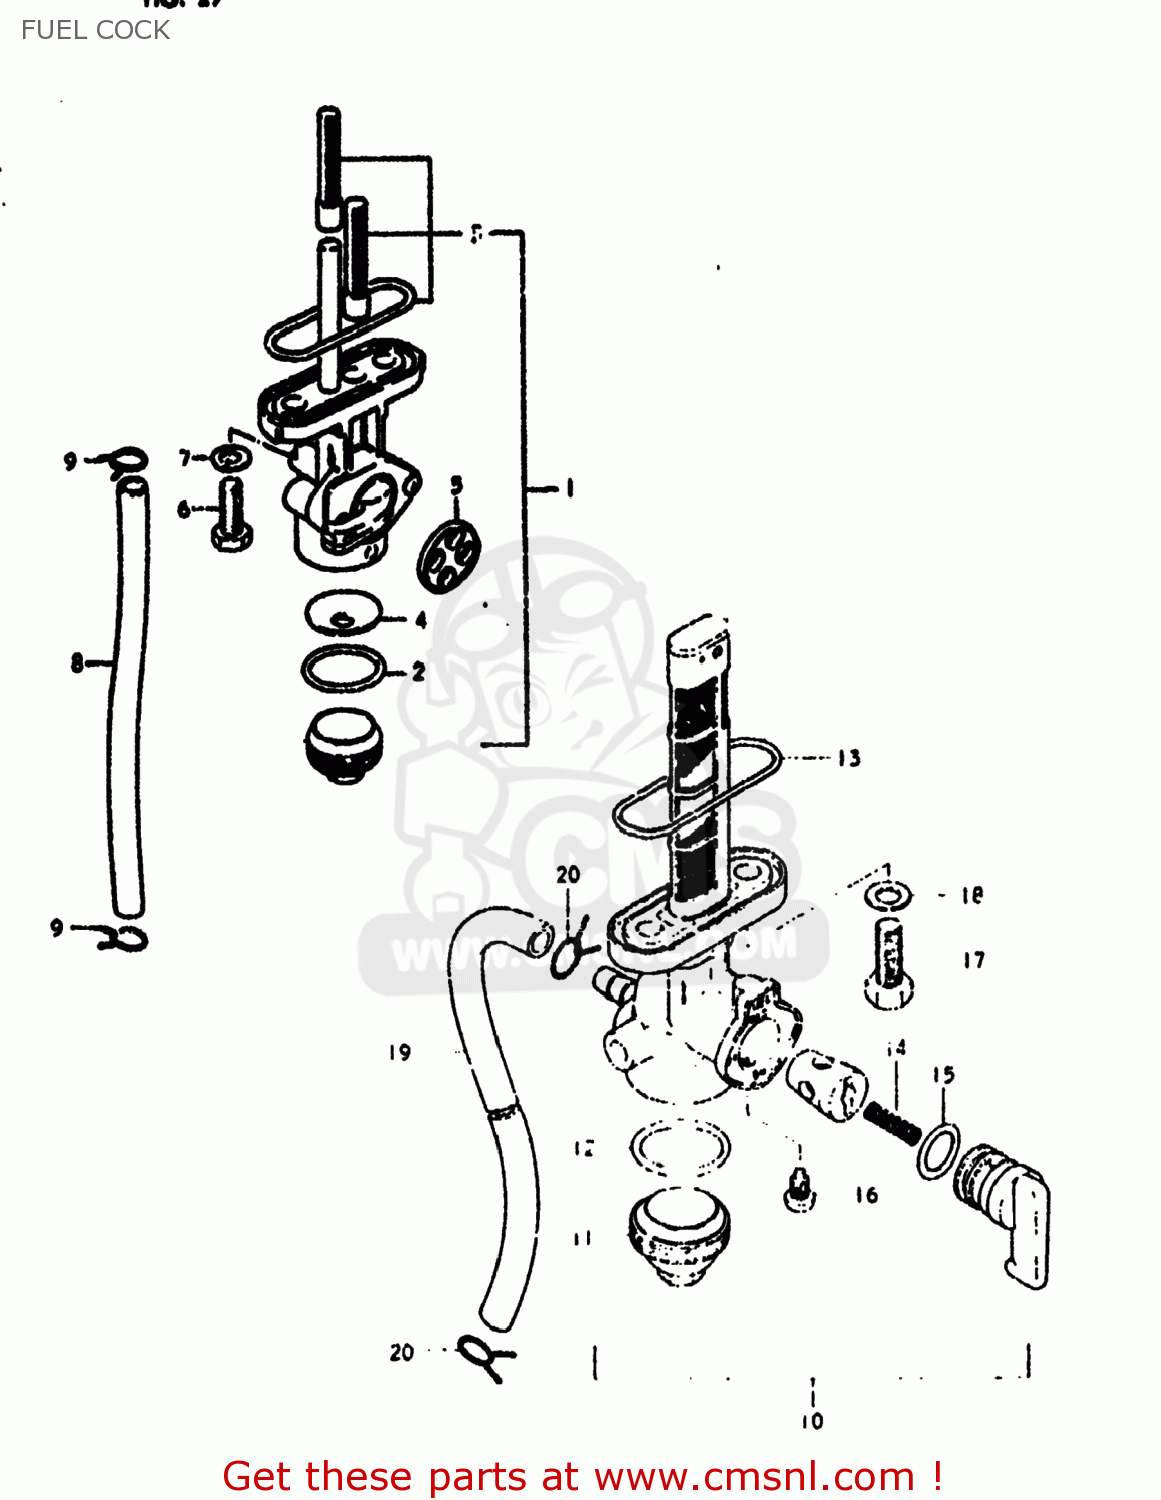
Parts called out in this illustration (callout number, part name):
1	COCK ASSEMBLY,FUEL
2	GASKET,FILTER (NAS)
3	NET,STRAINER
4	FILTER SET,FUEL COCK
5	GASKET,LEVER (NAS)
6	BOLT L:16
7	GASKET
8	HOSE
9	CLIP
10	COCK ASSEMBLY,FUEL
11	CUP,STRAINER
12	GASKET,FILTER (NAS)
13	O RING,FUEL COCK
14	SPRING
15	O-RING
16	SCREW
17	BOLT(6X20)
18	GASKET
19	HOSE
20	CLIP
